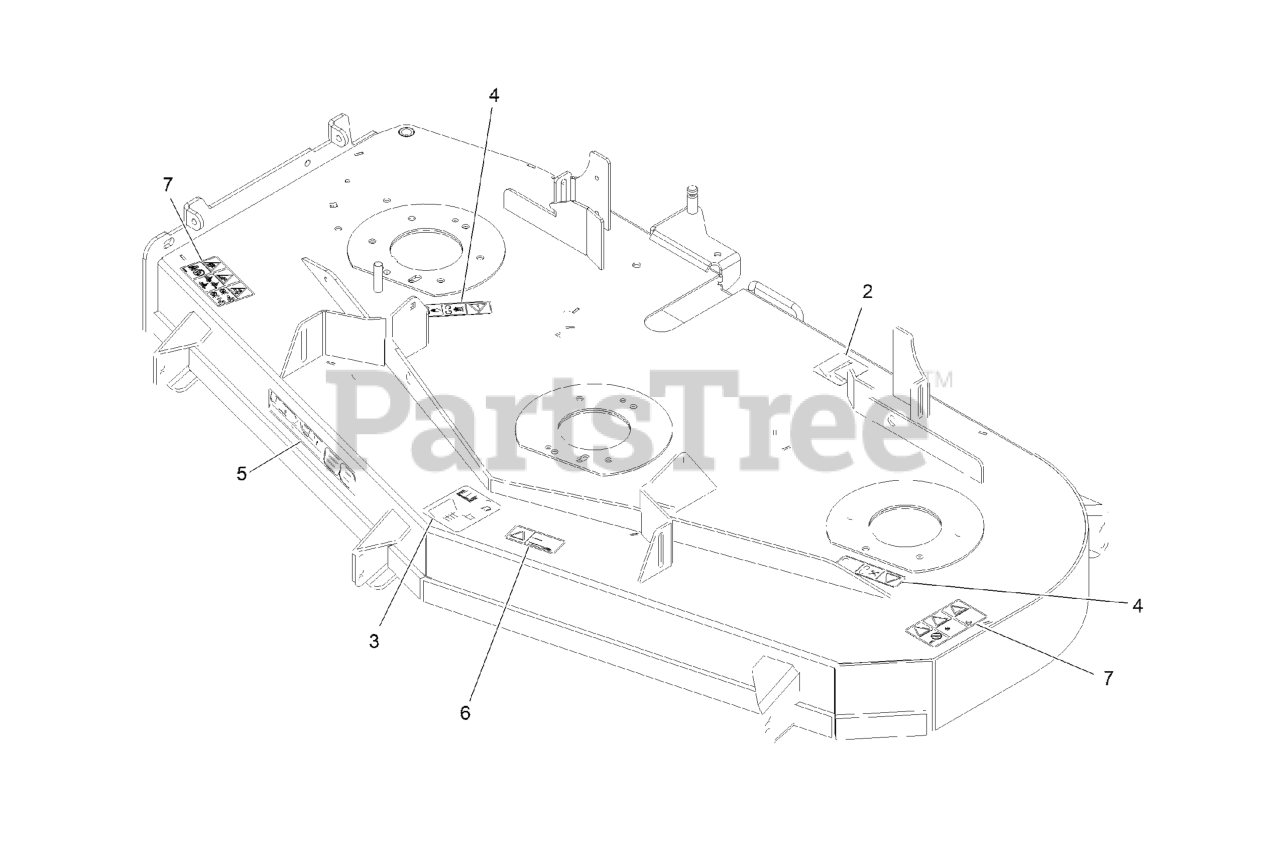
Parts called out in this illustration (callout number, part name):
2	DECAL-ROUTING, BELT
3	DECAL-ROLLER, ANTI-SCALP
4	DECAL-COVER, MISSING
5	DECAL-ULTRACUT 60 SERIES
6	DECAL-BOLT TORQUE
7	DECAL-DANGER THROWN OBJECTS
